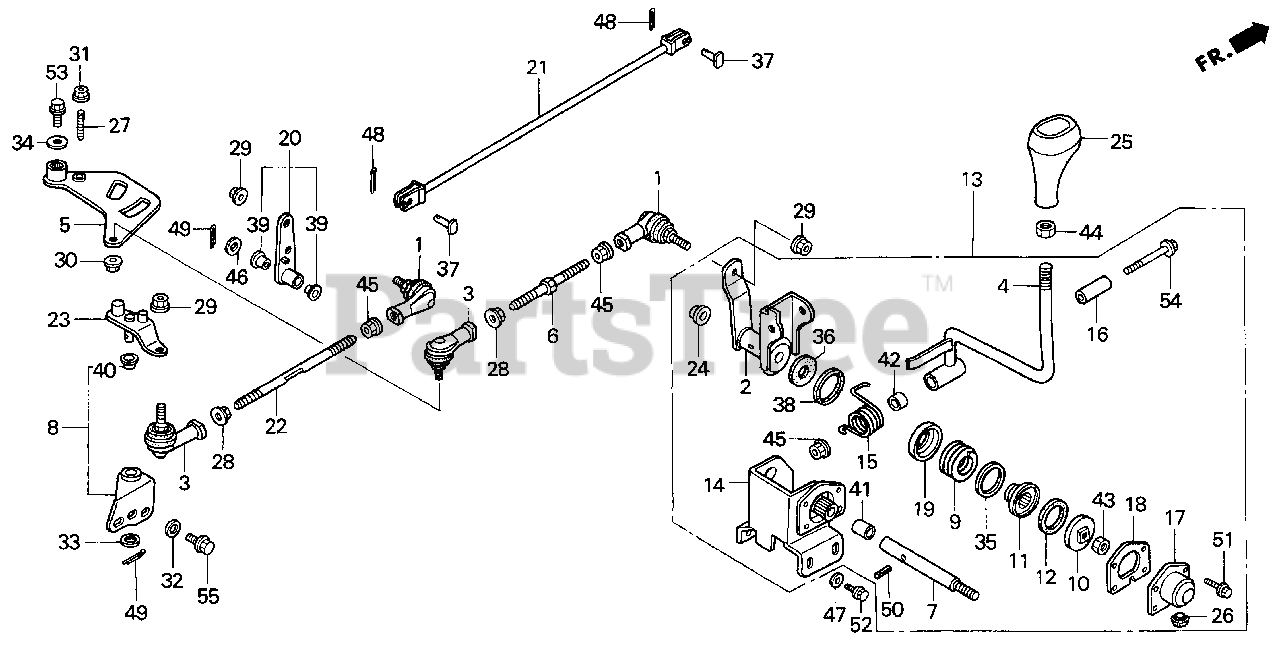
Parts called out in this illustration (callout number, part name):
1	JOINT, R. BALL
2	ARM, CHANGE
3	JOINT, L. BALL
4	LEVER, CHANGE
6	ROD, GEARSHIFT
7	SHAFT, CHANGE ARM
8	HOLDER ASSY., RETURN ARM
9	SPRING, FRICTION
10	WASHER, FRICTION SETTING
11	COLLAR, FRICTION SPRING
12	WASHER, FRICTION (15X40X3)
13	LEVER ASSY., CHANGE
14	HOLDER, CHANGE LEVER
15	SPRING, CHANGE LEVER
16	COLLAR, CHANGE LEVER JOINT
17	COVER, FRICTION
18	GASKET, FRICTION COVER
19	GUIDE, SPRING
20	ARM B ASSY., RETURN
21	ROD, RETURN (A)
22	ROD, RETURN (B)
23	ARM A, RETURN
24	BUSH (15X17X10)
25	KNOB, SHIFT LEVER
26	RUBBER, FUEL LID STOPPER
28	NUT, HEX. (8MM)
29	NUT, FLANGE (8MM)
30	NUT, FLANGE (8MM)
32	WASHER, PLAIN (10MM)
33	WASHER, PLAIN (16MM)
35	WASHER (31X46X1)
36	WASHER (15.5X36X2)
37	PIN (8X17.5)
39	BUSH (16X18X15)
40	BUSH (16X18X25)
41	BUSH (15X17X15)
42	COLLAR (13X19.1X10)
43	NUT, HEX. (10MM)
44	NUT, HEX. (12MM)
45	NUT, FLANGE (8MM)
46	WASHER, PLAIN (16MM)
48	PIN, COTTER (2.5MM)
49	PIN, COTTER (3.0X45)
50	PIN, SPRING (5X25)
51	BOLT, FLANGE (6X12)
52	BOLT-WASHER (8X16)
54	BOLT, FLANGE (8X80)
55	BOLT, FLANGE (10X25)
